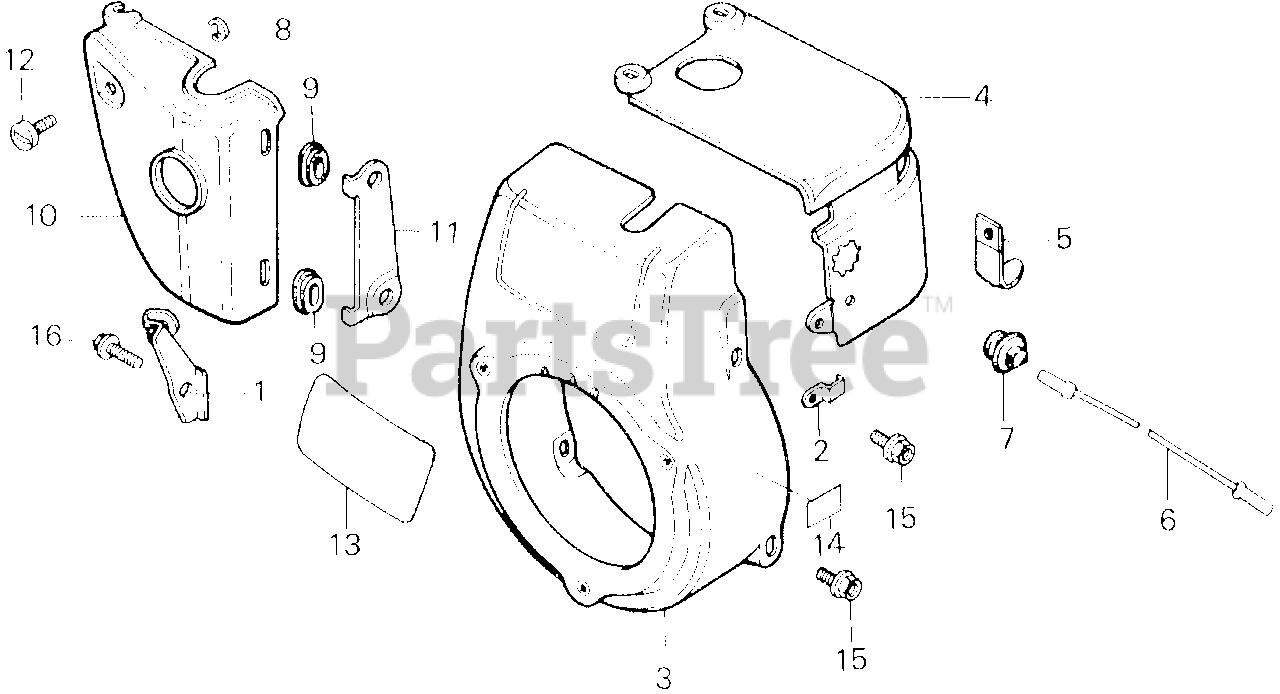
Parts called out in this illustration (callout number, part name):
1	HOLDER, THROTTLE
2	CLAMP, FUEL TUBE (NOT AVAILABLE)
3	COVER, FAN *R8* (BRIGHT RED) (NOT AVAILABLE)
4	COVER, SIDE *R8* (BRIGHT RED)
5	CLAMP, WIRE
6	WIRE A, ENGINE SWITCH
7	GROMMET, COVER (NOT AVAILABLE)
8	E-CLIP (NOT AVAILABLE)
9	RUBBER, CHAIN CASE SETTING
10	COVER, ENGINE SIDE *R8* (BRIGHT RED) (NOT AVAILABLE)
11	STAY, SIDE COVER
12	SCREW, SIDE COVER
13	MARK, FAN COVER
14	LABEL, COMPLIANCE
15	BOLT, FLANGE (6X12)
16	BOLT, FLANGE (6X16)
